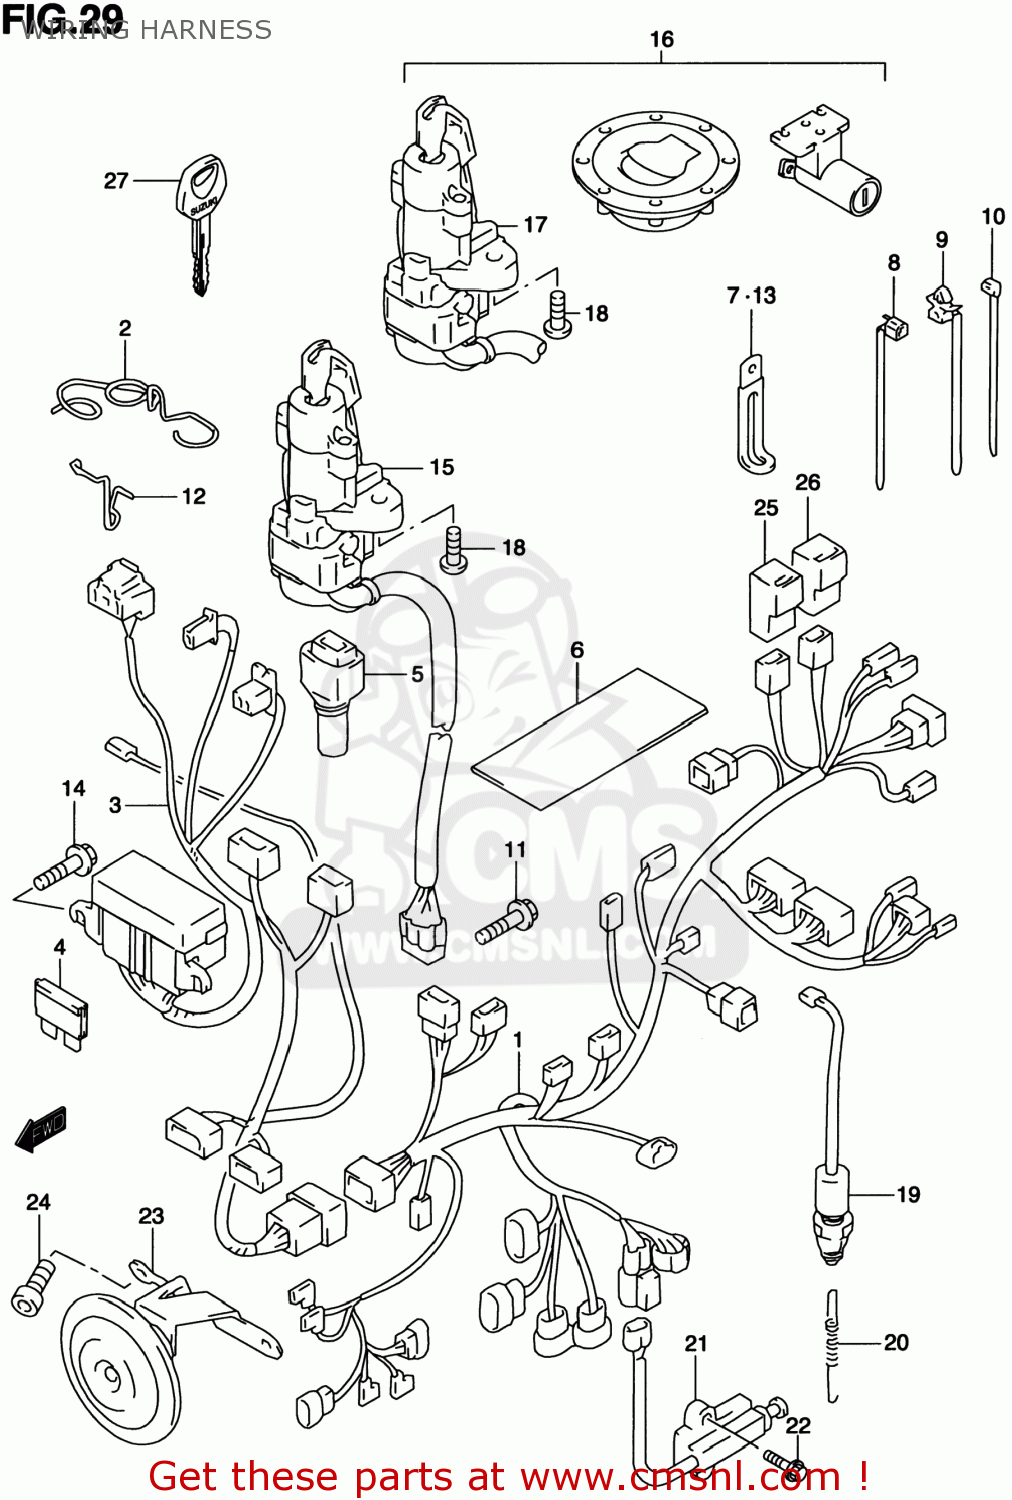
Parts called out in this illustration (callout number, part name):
1	HARNESS,WIRING NO.1
2	GUIDE,WIRING HARNESS
3	HARNESS,WIRING NO.2
4	FUSE(10A)
5	COVER,SPEEDOMETER COUPLER
6	PROTECTOR,WIRING HARNESS
7	CLAMP(L:45)
8	CLAMP(L:95)
9	CLAMP
10	CLAMP(L:145)
11	BOLT
12	STOPPER,FUSE BOX
13	CLAMP(L:65)
14	SCREW 6X12
15	LOCK ASSY,STEERING
16	LOCK SET
17	LOCK ASSY,STEERING
18	BOLT(8X20)
19	SWITCH ASSY,STOP LAMP
20	SPRING
21	SWITCH ASSY,SIDE STAND WARNING
22	BOLT
23	HORN ASSY
24	BOLT
25	RELAY ASSY
26	RELAY ASSY
27	KEY,BLANK
